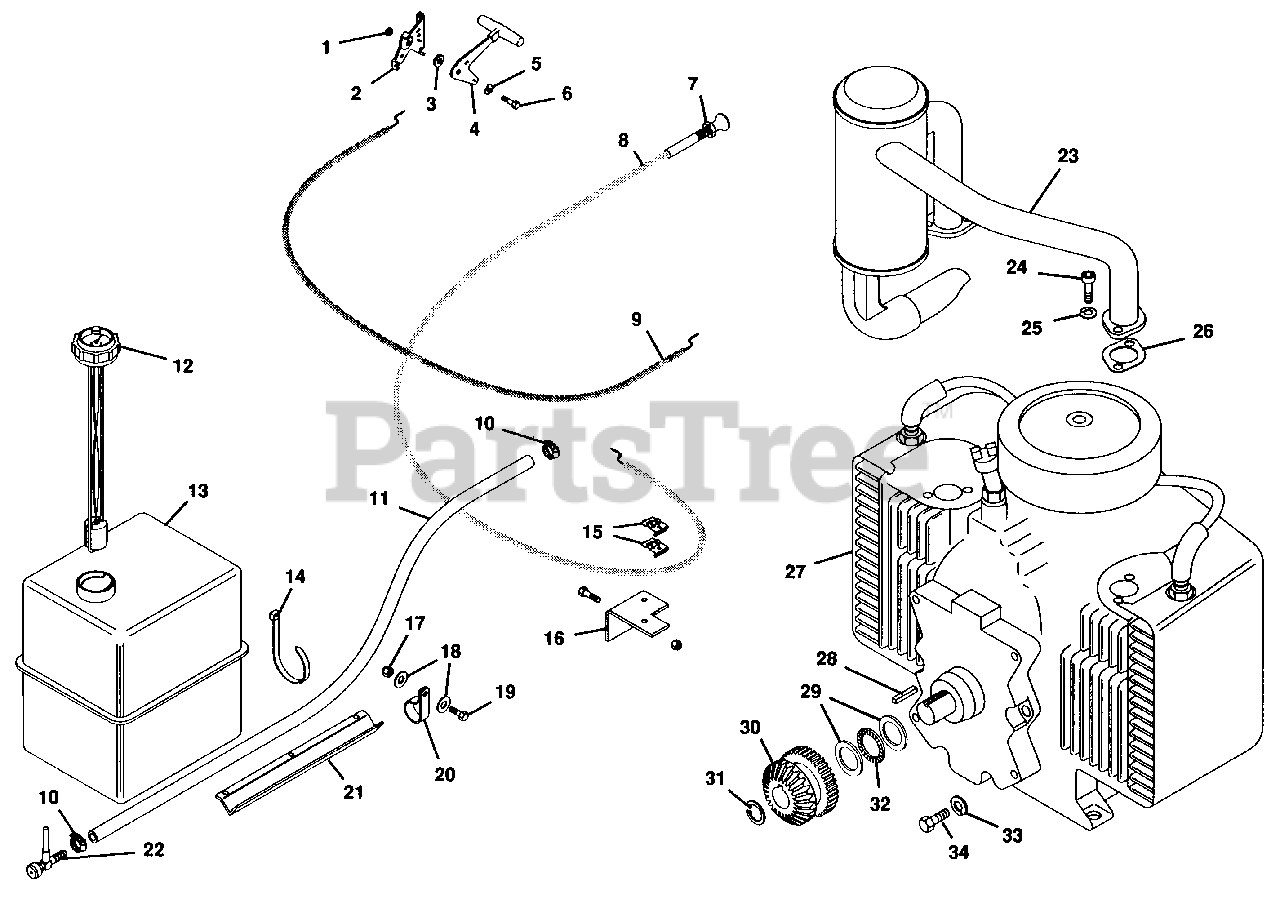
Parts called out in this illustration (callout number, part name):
1	NUT, LOCK 1/4-28
2	BRACKET, MOUNTING
3	WASHER, FRICTION
4	ASSEMBLY, KNOB AND LEVER
5	WASHER, SPRING
6	BOLT, HEX 1/4-28X.75
7	NUT, JAM 3/8-24 HEX
8	CONTROL, CHOKE
9	ASSEMBLY, CHOKE CONDUIT
10	CLAMP, HOSE
11	LINE, FUEL
12	GAUGE, GAS
13	TANK, FUEL
14	TIE, CABLE
15	CLIP, SPEED
16	BRACKET, THROTTLE AND CHOKE
17	NUT, LOCK 5/16-18
18	WASHER, FLAT .343X.688X.065
19	BOLT, HEX 5/16-18X1.00
20	CLAMP, NYLON
21	SHIELD, HEAT
22	VALVE, FUEL 90 DEG. REVERSE FLOW
23	MUFFLER, EXHAUST
24	SCREW, CAP 5/16-18X.75 SHD
25	WASHER, LOCK 5/16 REG.
26	GASKET, EXHAUST
27	ENGINE, 16 H.P.
27	ENGINE, 18 H.P.
27	ENGINE, 20 H.P.
28	KEY, SQUARE .250X1.250
29	RACE, BRG 1.125X1.750X.123/.126
30	GEAR, SPUR AND BEVEL, INPUT
31	RING, RETAINING 1.125 SHAFT
32	BEARING, THRUST 1.127X1.740X.078
33	WASHER, LOCK 1/2 REG.
34	BOLT, HEX 1/2-13X1.75
NS	NUT, LOCK 10-32
NS	SCREW, MACHINE 10-32X.50 PHD
